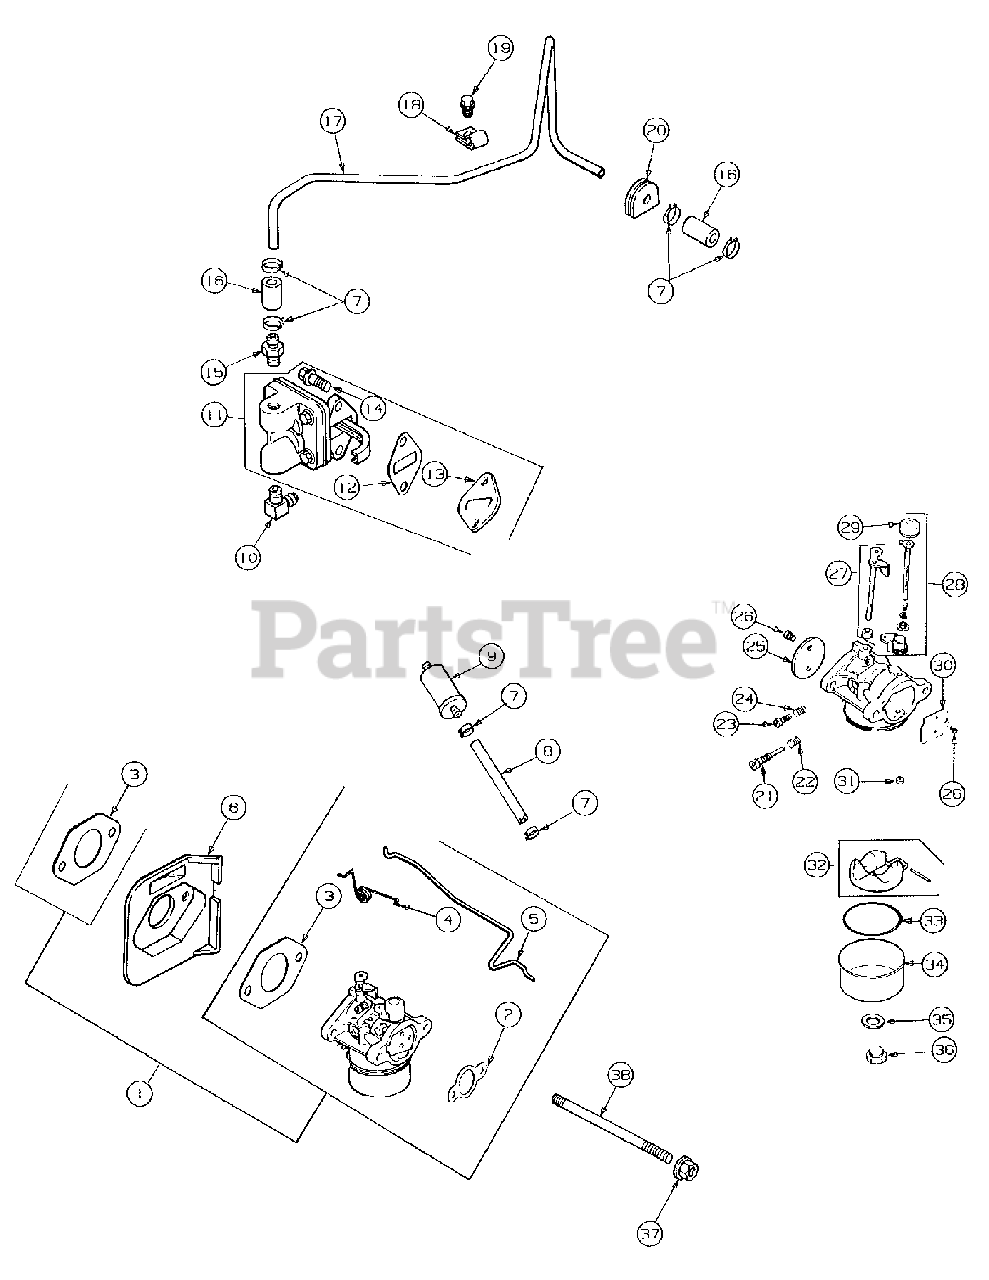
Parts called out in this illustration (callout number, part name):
1	Kit, Carburetor
2	Gasket, Air Cleaner
3	Gasket, Carburetor
4	Spring, Choke Return
5	Linkage,Choke
6	Deflector, Heat
7	Clamp, Fuel Line
8	Line, Fuel 3''
9	Filter, Fuel
10	Connector, 90 Deg
11	Kit, Fuel Pump
12	Gasket, Fuel Pump
13	Spacer, Fuel Pump
14	Screw, Fuel Pump Mtg
15	Connector, Straight
16	Line, Fuel, 1-1/4''
18	Clamp, Fuel Line
19	Screw, Fuel Line Connecting
21	Needle Idle Fuel Adj.
22	Spring, Idle Fuel
23	Screw, Idle Speed Adj.
24	Spring, Idle Speed
25	Plate, Throttle
26	Screw, Throttle & Choke Plate
27	Shaft, Throttle w/Lever & Seal
28	Kit, Choke Shaft Repair
29	Cap, Choke Lever
33	Gasket, Bowl
35	Gasket, Bowl Ret Screw
36	Screw, Fuel Bowl
37	Nut, Carburetor, M6 x 1.0
38	Stud, Carburetor,M6 x 1.0 x 110
